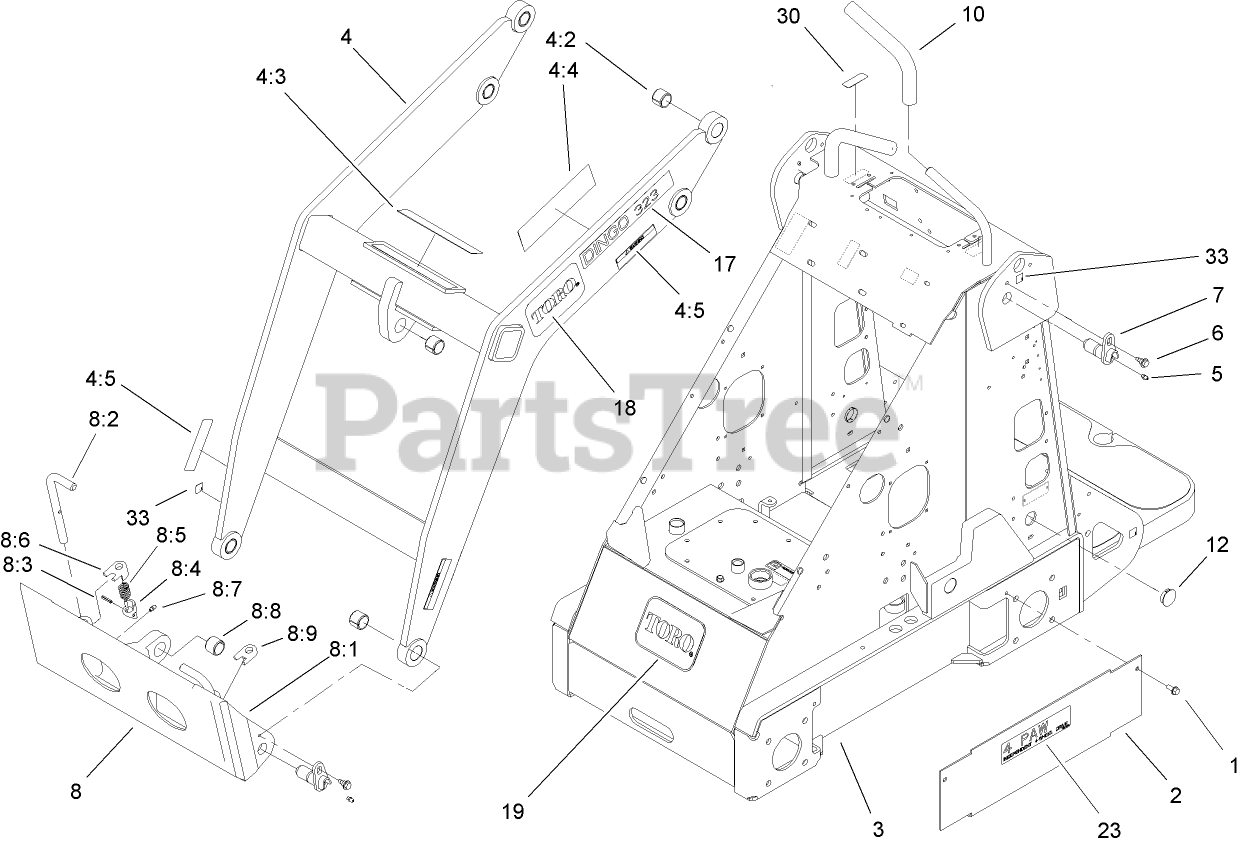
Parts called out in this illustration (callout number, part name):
1	SCREW-HWHTF
2	COVER-HOSE
3	FRAME ASM
4	LOADER ASM
4:2	BUSHING-TENSION
4:3	DECAL-CAUTION
4:4	DECAL-DANGER
4:5	DECAL-PINCH
5	FITTING-GREASE
6	BOLT-SHOULDER
7	PIN-PIVOT
8	QUICK ATTACH ASM
8:1	MOUNT-ATTACH, QUICK
8:2	PIN-LOCKING
8:3	PIN-GROOVED
8:5	SPRING-COMPRESSION
8:6	STOP-RH
8:7	FITTING-GREASE
8:8	BUSHING-TENSION
8:9	STOP-LH
10	GRIP-CUSHION
12	PLUG-HOLE
17	Decal
18	DECAL
19	DECAL
30	DECAL-CHOKE
33	DECAL-POINT, LIFT
